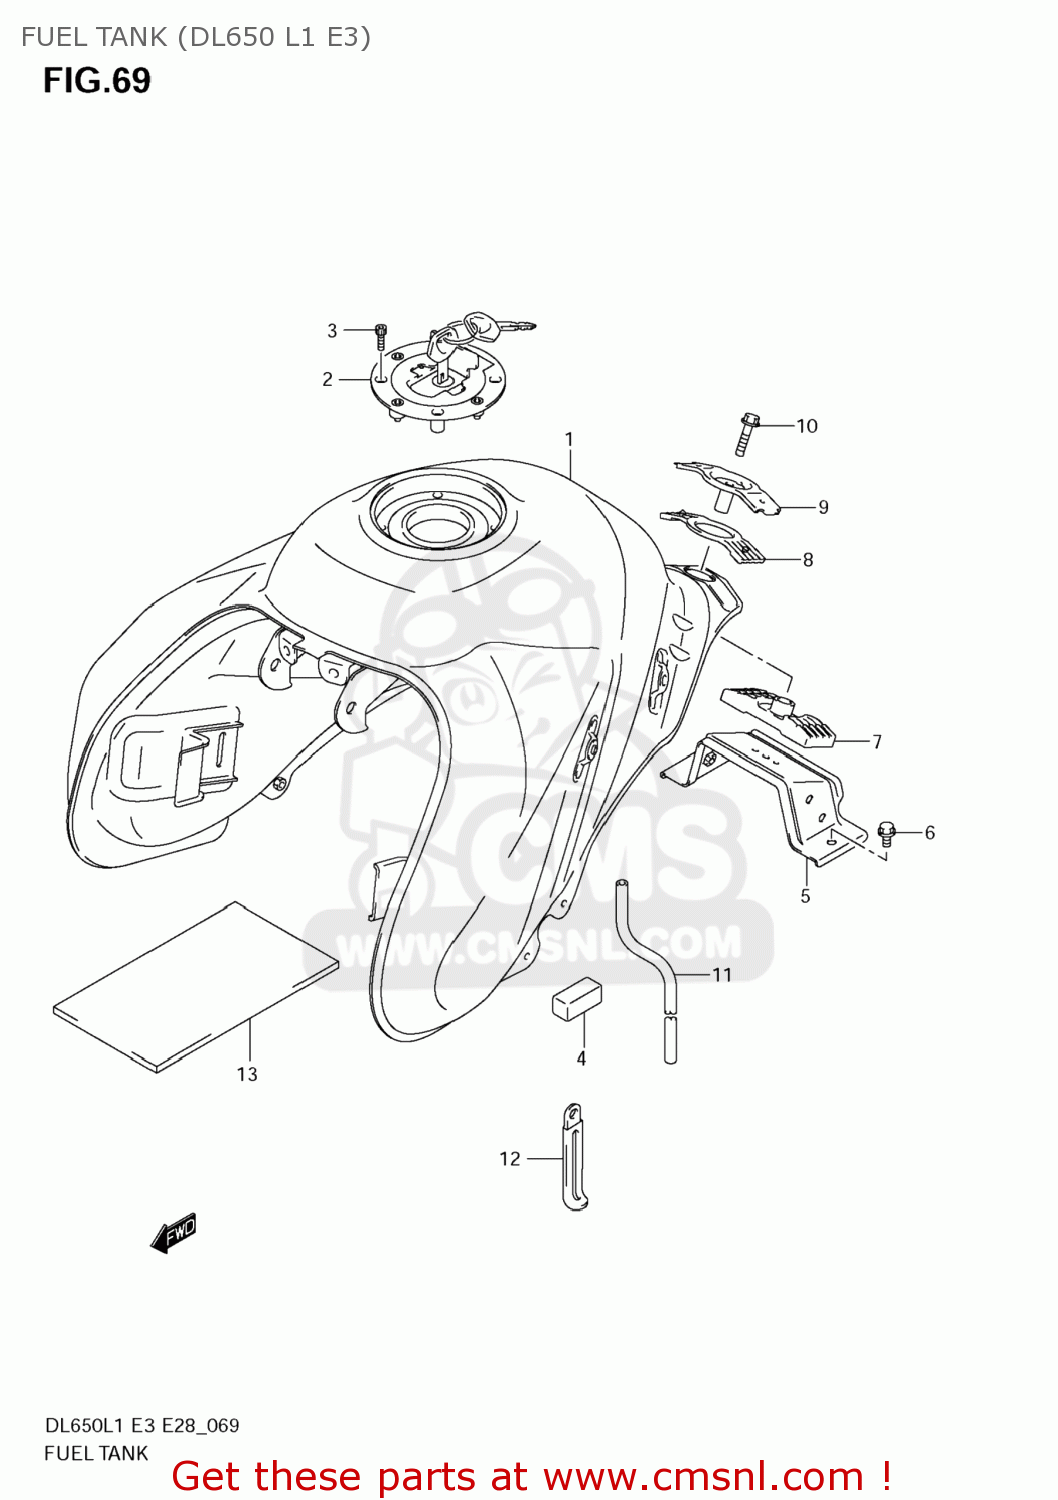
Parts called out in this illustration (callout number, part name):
1	TANK ASSY, FUEL
2	CAP SET,FUEL TANK
3	BOLT(5X20)
4	CUSHION,FUEL TANK SIDE
5	BRACKET,FUEL TANK RR
6	BOLT
7	CUSHION,FUEL TANK RR LWR
8	CUSHION,FUEL TANK RR UPR
9	BRACKET,FUEL TANK RR UP
10	BOLT
11	HOSE,FUEL TANK WATER DRAIN
12	CLAMP(L:80)
13	SHIELD,FUEL TANK CTR
